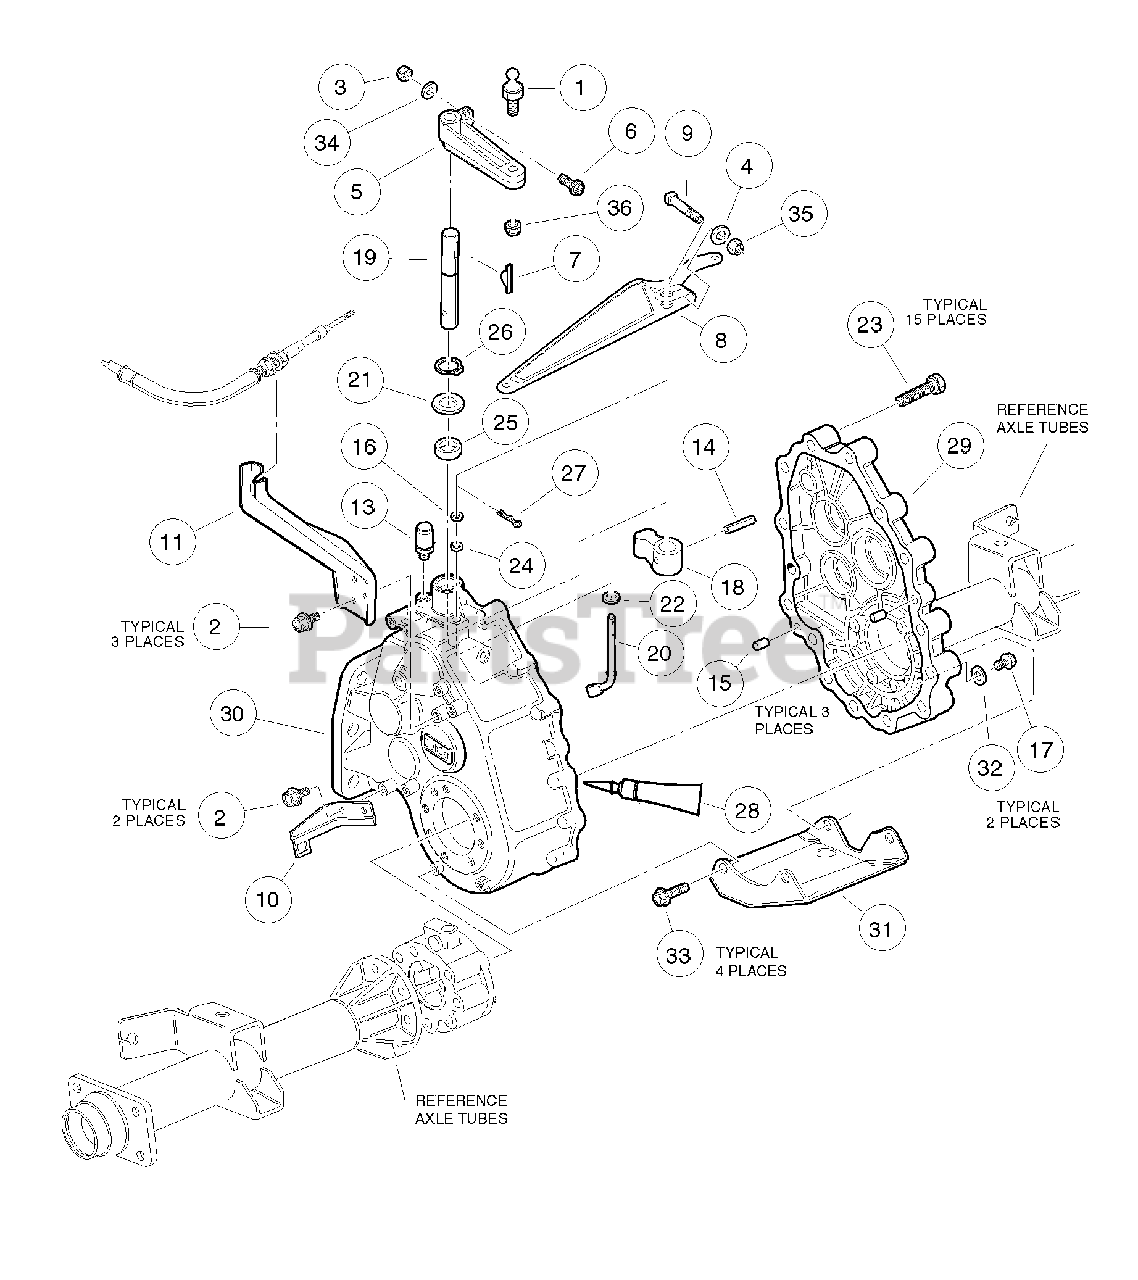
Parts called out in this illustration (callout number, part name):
1	Stud, 1/4-28 X 0.560 Ball
2	Screw, 1/4 X 0.625 Hex-Head
3	Locknut, #10-32 Nylon Insert
4	Washer, 1/4 Flat
5	Lever, Transmission Shift
6	Screw, #10-32 X 0.75, Hex-Head Machine
7	Key, Woodruff
8	Arm, Governor
9	Screw, 1/4-20 X 1.00 Square-Head
10	Differential Lock Bracket
11	Bracket, Shifter
12	Transaxle, Hd, 15.51 Ratio
15	Pin, Dowel
16	Washer, M6 Flat
17	Plug, Drain
18	Lever, Change
19	Shaft - Change
23	Screw, M8-1.25 X 40mm Hex-Head
27	Pin, Cotter
28	Liquid Gasket
29	Case, Gear, Right Mc012
30	Gear Case, Left
31	Guard, Transaxle
34	Washer, #10 Type A Flat
35	Locknut, 1/4-20 Nylon Insert
36	Locknut, 1/4-28 Nylon Insert
